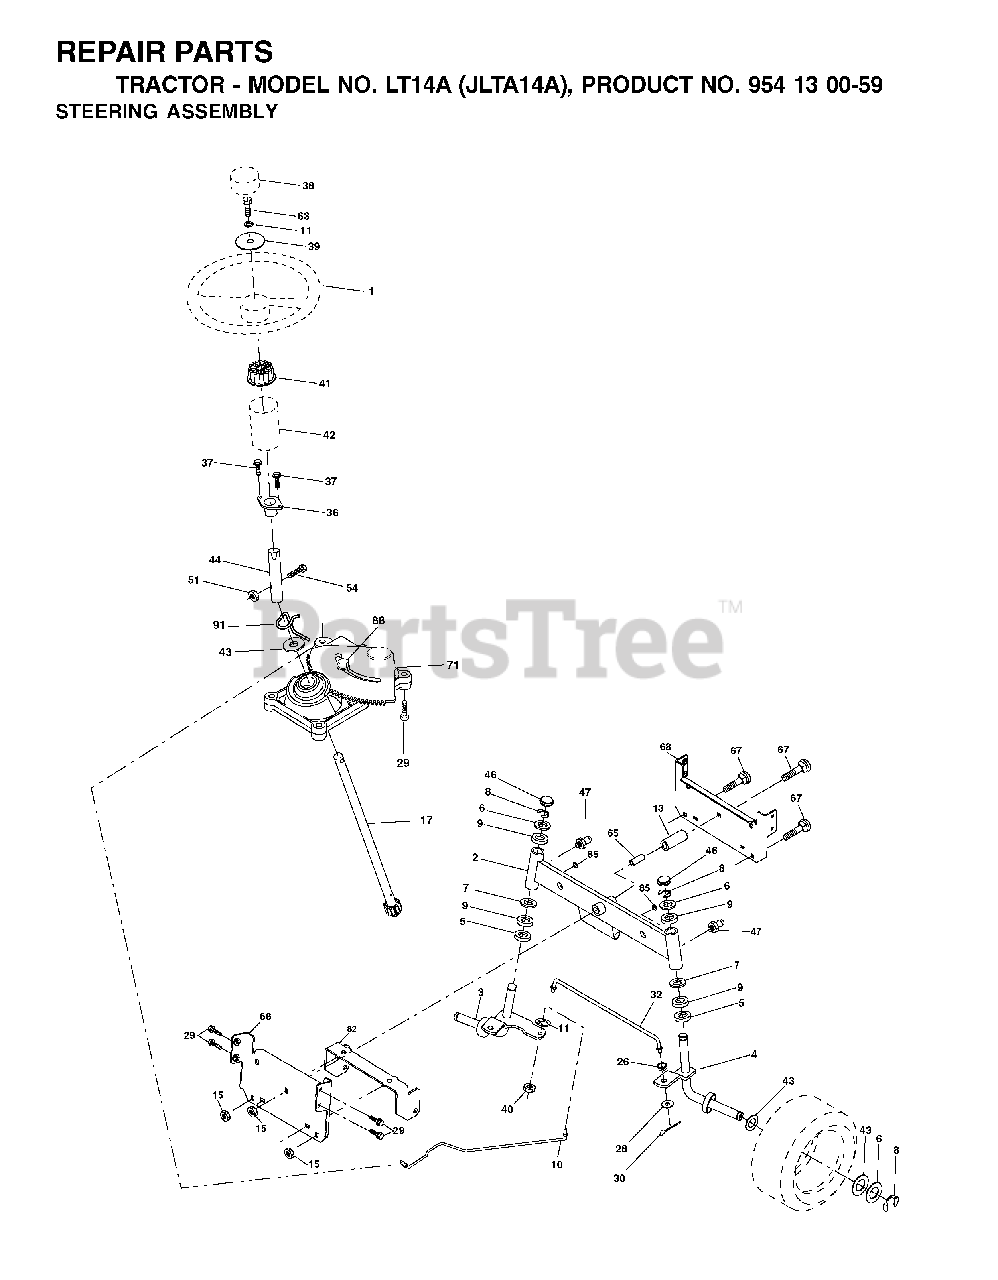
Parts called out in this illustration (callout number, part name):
2	AXLE ASM.
3	SPINDLE.ASM.LH.15"TIRES
4	SPINDLE.ASM.RH.15"TIRES
8	RING CLIP
9	BRNG T
10	DRAGLINK.15".TIRES.2001
11	WASHER, LOCK 3/8
13	TUBE, PIVOT AXLE
17	SHAFT ASM
26	BUSHING.DRAGLINK
28	WASHER
29	SCREW 3/8-16X3/4
30	COTTER PIN
32	TIE ROD
36	BUSHING, STEERING
39	WASHER 13/32 X 2-3/8 X 12 GA
40	GRIPCO NUT
41	STEERING WHEEL ADAPTOR
42	BOOT.STEERING.SHAFT.BLACK
44	EXT SHAFT STEERING
46	CAP.SPINDLE
47	ZERK M
51	NUT.71038.31-18.HEX.NYLOCK
54	BOLT.5/16-18X1-1/4 FULL.THREAD
63	BOLT
65	SPACER BRACE AXLE
67	BOLT
68	BRACE.AXLE.15"TIRES
71	STEERING ASM
82	BRACKET
85	FASTENER.XMAS.TREE
88	BOLT, SHOULDER 7/16-20
91	CLIP.STEERING
